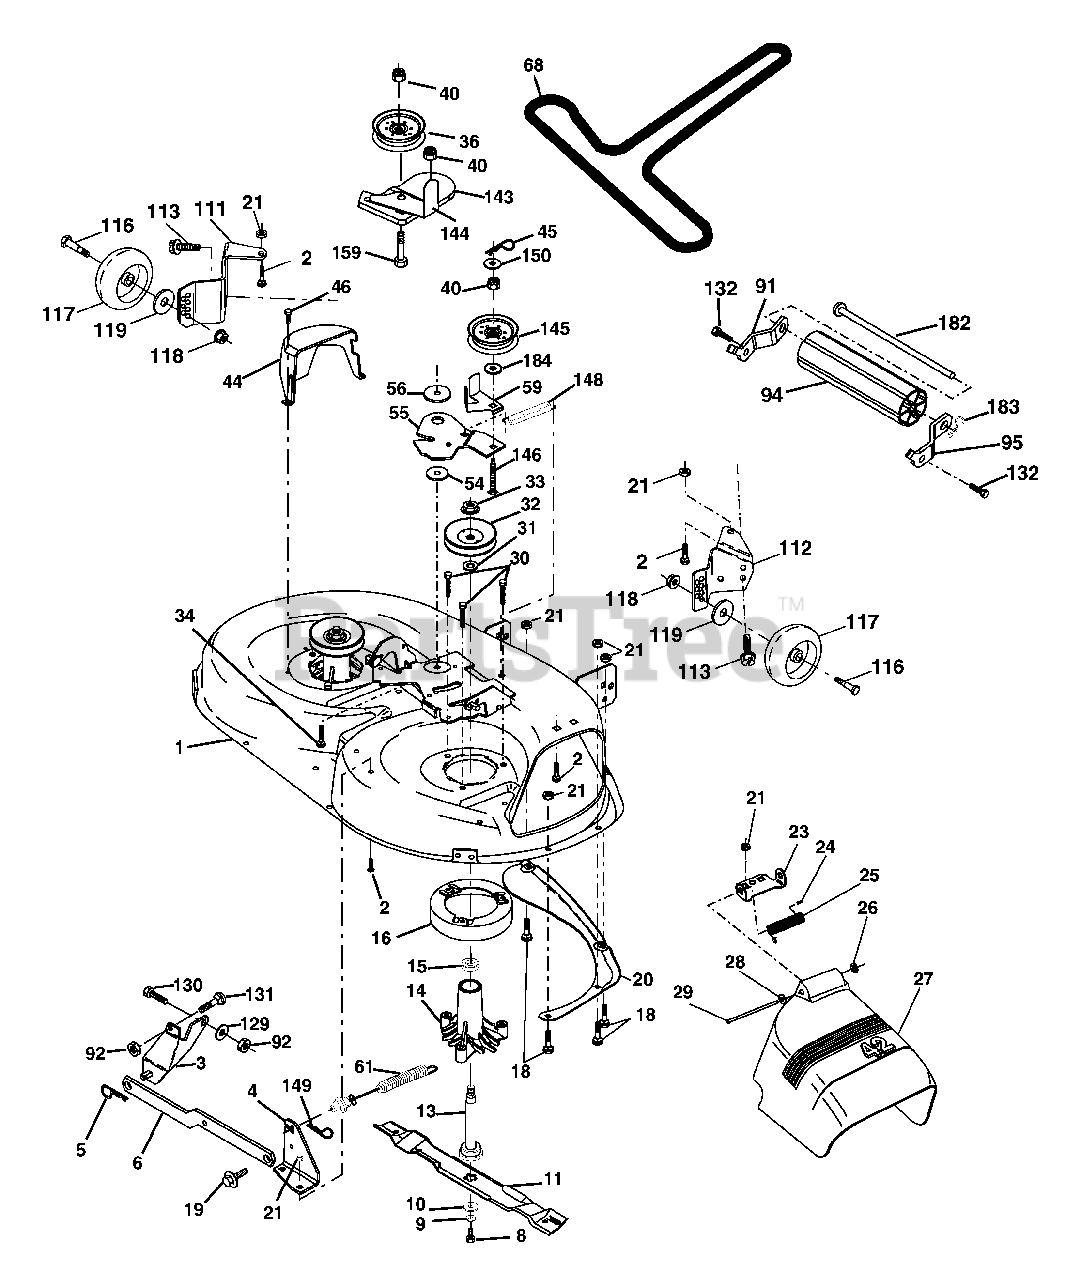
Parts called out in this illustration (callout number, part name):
1	Mower Deck Assembly, 42"
2	Bolt
3	Bracket Asm Fr. Sway Bar 3/42
4	Bracket Asm Deck 42" Sway Bar
5	Retainer Spring
6	Bar Sway Deck
8	Bolt 3/8-24 x 1.25 Gr. 8 patched
9	Washer, Lock
10	Washer, Hardened
11	Blade Mower 42" Hi-Lift
11	Blade, Mulching 42" Std
11	Blade Mulching 42" Premium
13	Shaft Assembly, Mandrel, Vented
14	Housing, Mandrel, Vented
15	Bearing, Ball, Mandrel
16	Stripper, Mandrel Deck
18	Bolt, Carriage 5/16-18 x 5/8
19	Bolt, Shoulder
20	Baffle, Vortex
21	Nut
23	Bracket, Deflector Mower 42"
24	Cap, Sleeve 80 x 112 Blk Mower
25	Spring, Torsion, Deflector 2 52
26	Nut, Push Phos & Oil
27	Shield, Deflector 42" Blk
28	Washer 11/32 x 5/8 x 16 Ga.
29	Rod, Hinge 42" 6 75 W/G
30	Screw Thdrol
31	Washer, Spacer Mower Vented
32	Pulley, Mandrel
33	Nut, Toplock
34	Bolt Carr SH 3/8-16 x 1-1/2 Gr.5
36	Pulley, Idler, Flat
40	Nut Lock 3/8-16
44	Guard, Mandrel, LH
45	Retainer
46	Screw Thd Roll 1/4-20 x 5/8
54	Washer, Hardened
55	Arm, Idler
56	Spacer, Retainer
59	Guard TUV Idler
61	Spring Ext Elect Clutch
68	V-Belt, 42" Mower
91	Bracket Roller Nose LH
92	Nut Lock Hex W/Ins 3/8-16 UNC
94	Roller Nose
95	Bracket Roller Nose RH
111	Bracket Wheel Guage LH
112	Bracket Wheel Guage RH
113	Screw 5/16-18
116	Bolt, Shoulder
117	Wheel Gauge
118	Nut Centerlock 3/8-16
119	Washer 3/8 x 7/8 x 14 Ga.
129	Washer 13/32 x 13/16 x 12 Ga.
130	Bolt Fin Hex 3/8-16 UNC x 1 Gr. 5
131	Bolt RDHD SQNK 3/8-16 UNC x 1
132	Rod Roller Nose
143	Bracket Arm Idler 42"
144	Keeper Belt 42" Clutch Cable
145	Pulley Idler Flat
146	Bolt Carriage Idler
147	Spring Extension
148	Spring Return Idler
149	Retainer Spring Yellow
150	Washer 9/32 x 3/4 x 10 Ga.
159	Bolt Rdhd Sqn 3/8-16 unc x 1-3/4
182	Rod roller nose
183	Retainer Spring
184	Washer 13/32 x 7/8 x 10 Ga.
